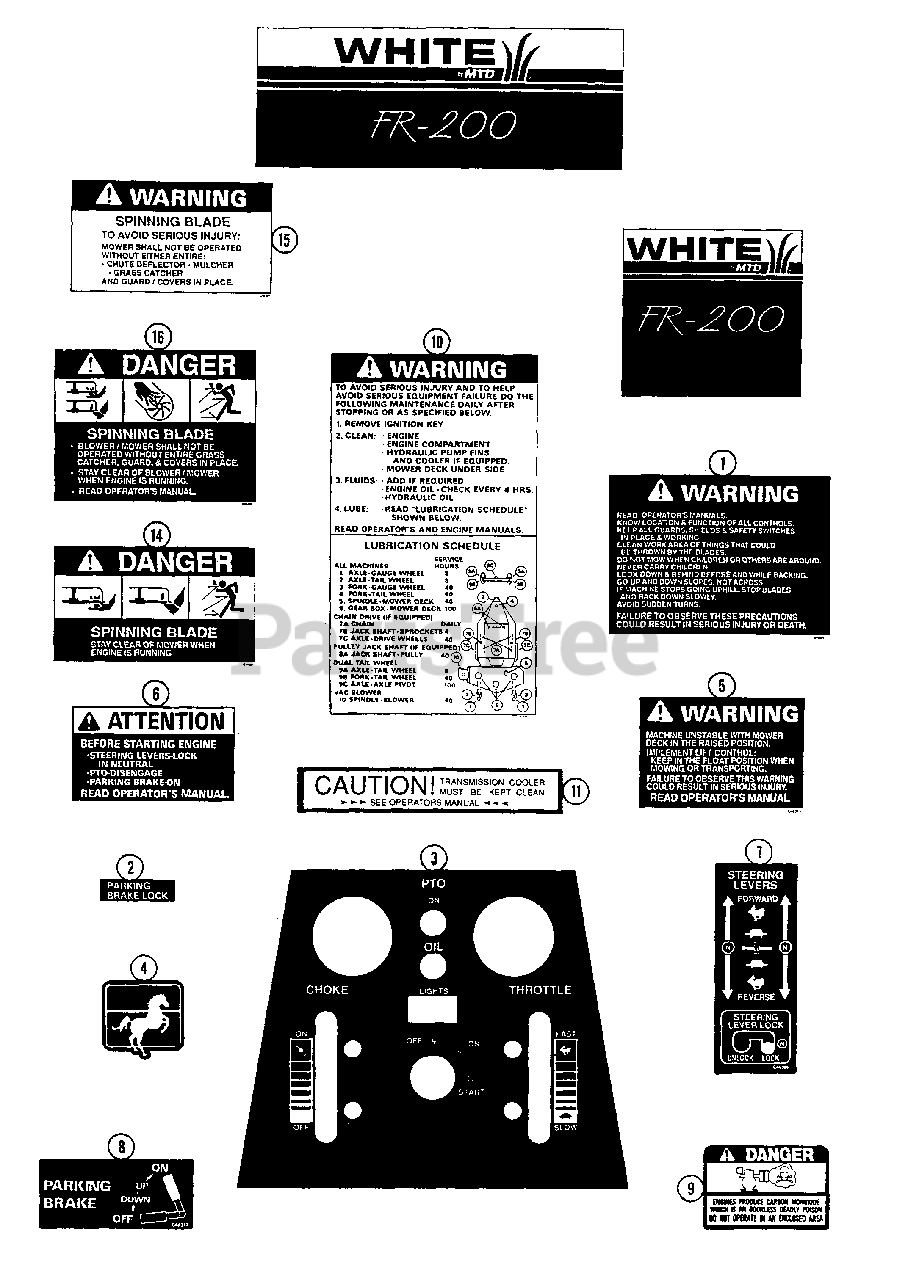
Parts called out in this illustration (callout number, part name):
1	DECAL - WARNING
2	DECAL - brake lock
3	DECAL - instrument panel
4	MEDALLION - White "horse"
5	DECAL - "WARNING" lift control
6	DECAL - caution interlock
7	DECAL - unlock/lock
8	DECAL- run/park
9	DECAL - danger carbon monoxide
10	DECAL - lubrication
11	DECAL - clean cooler
14	DECAL "DANGER" spinning blade
15	DECAL "WARNING" spinning blade
16	DECAL "DANGER"
